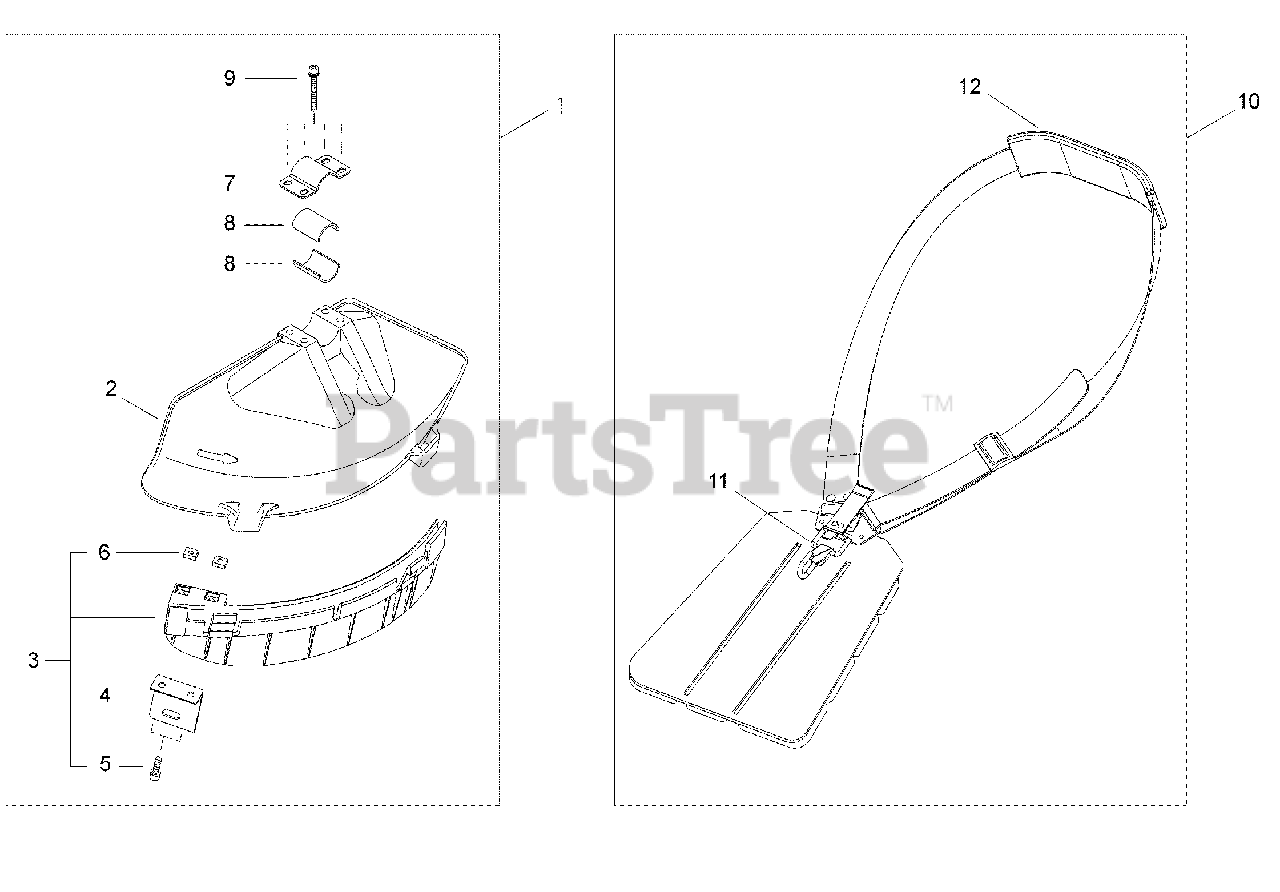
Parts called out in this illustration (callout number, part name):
1	DEBRIS SHIELD KIT
2	SHIELD, DEBRIS
3	SHIELD GUARD KIT
4	KNIFE, TRIMMER LINE
5	SCREW - 5X16
6	NUT - 5
7	CLAMP - UPPER
8	SPACER
9	SCREW - 5X45
10	HARNESS ASSY
11	HOOK
12	PAD
